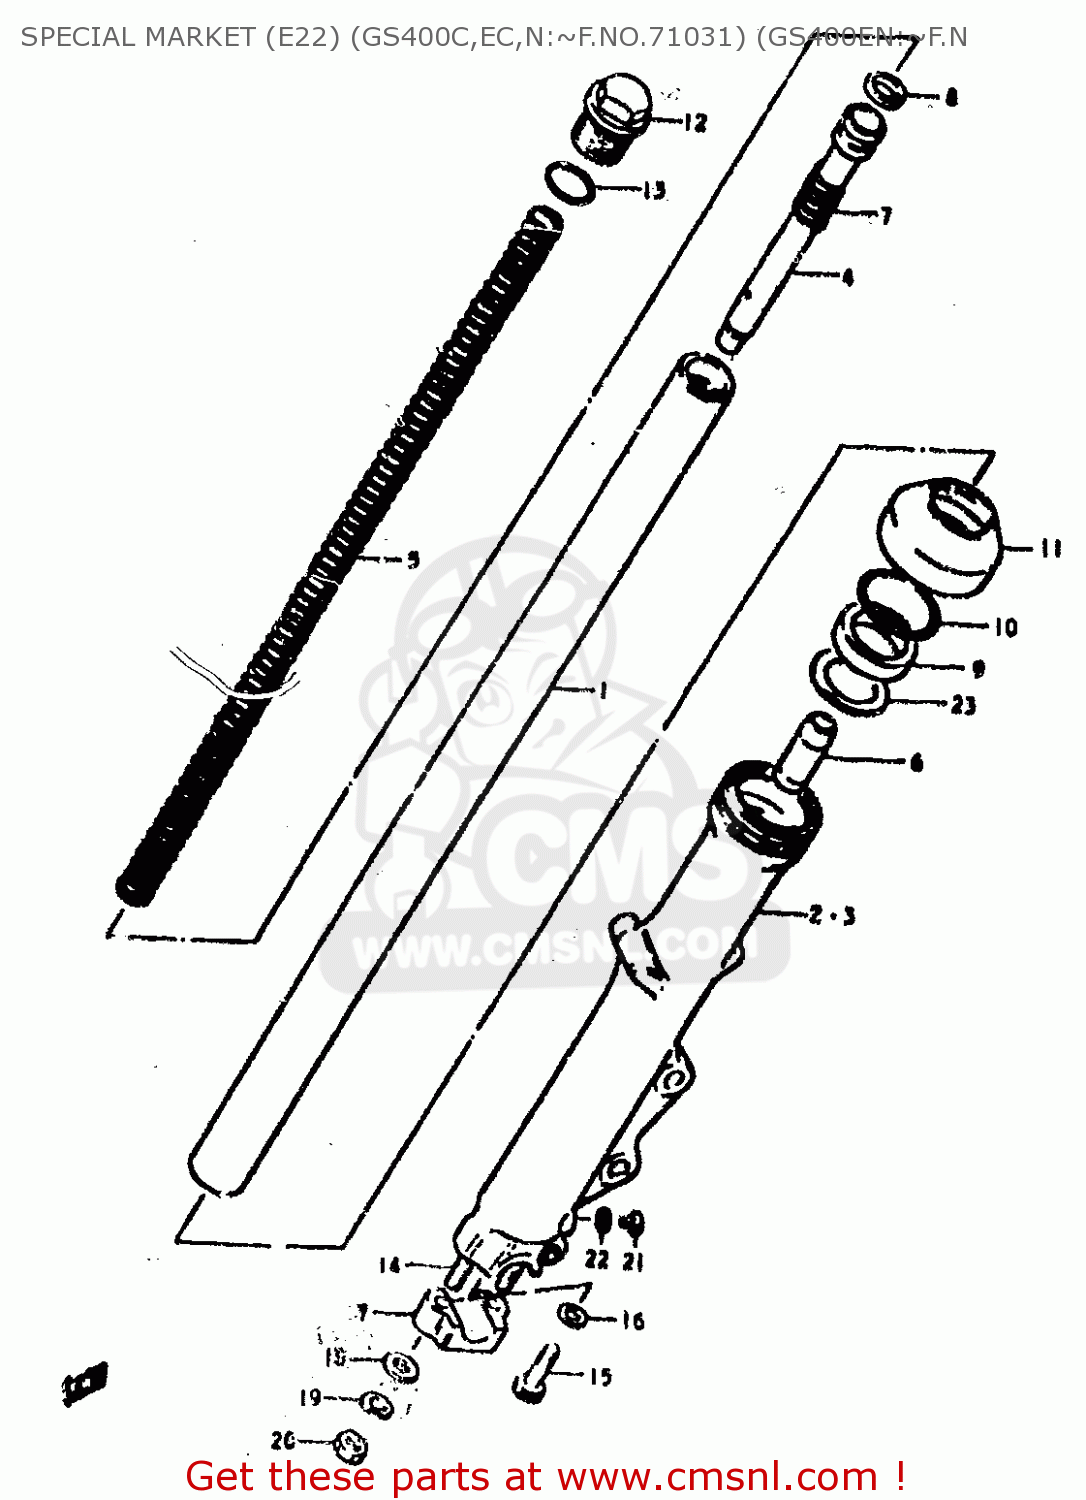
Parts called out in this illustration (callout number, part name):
1	TUBE,INNER
2	TUBE,FORK,LEFT,OUTER
3	TUBE,FORK,OUTER,RIGHT
4	CYLINDER,FRONT FORK
5	SPRING
6	PIECE,OIL LOCK
7	SPRING,REBOUND
8	RING,PISTON
9	OIL SEAL,FRONT FORK
10	CIRCLIP,FORK OIL SEAL
11	BOOT
12	BOLT
13	O RING
14	STUD 8X25
15	BOLT
16	GASKET (NAS)
17	HOLDER,AXLE
18	WASHER
19	LOCK WASHER
20	NUT
21	SCREW
22	GASKET (NAS)
23	SPACER,OIL SEAL
